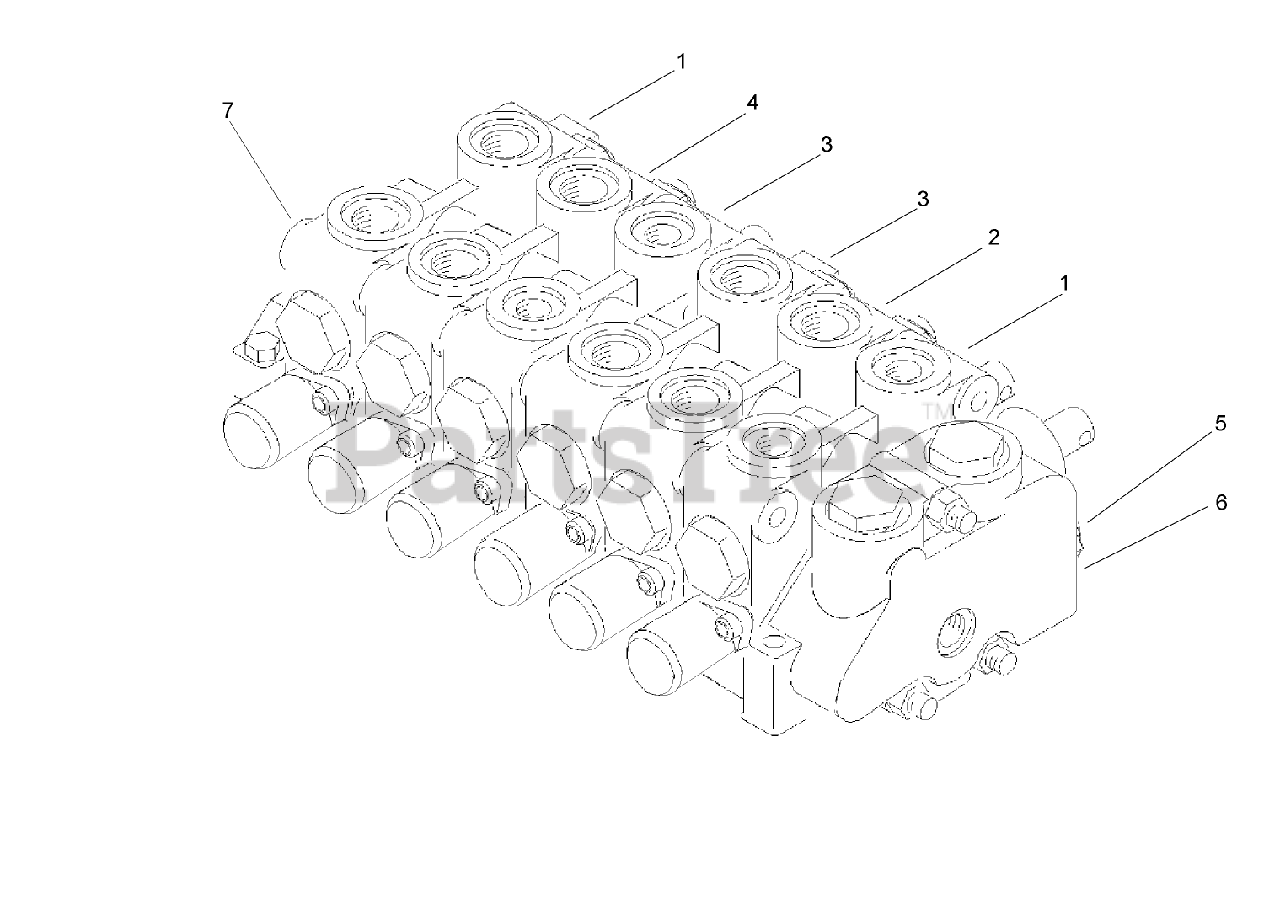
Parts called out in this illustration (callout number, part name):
1	SECTION-BUCKET, SWING
2	SECTION-BOOM
3	SECTION-VALVE, STABILIZER
4	SECTION-DIPPER
5	VALVE-RELIEF
6	COVER-LEFT
7	COVER-END, RH
